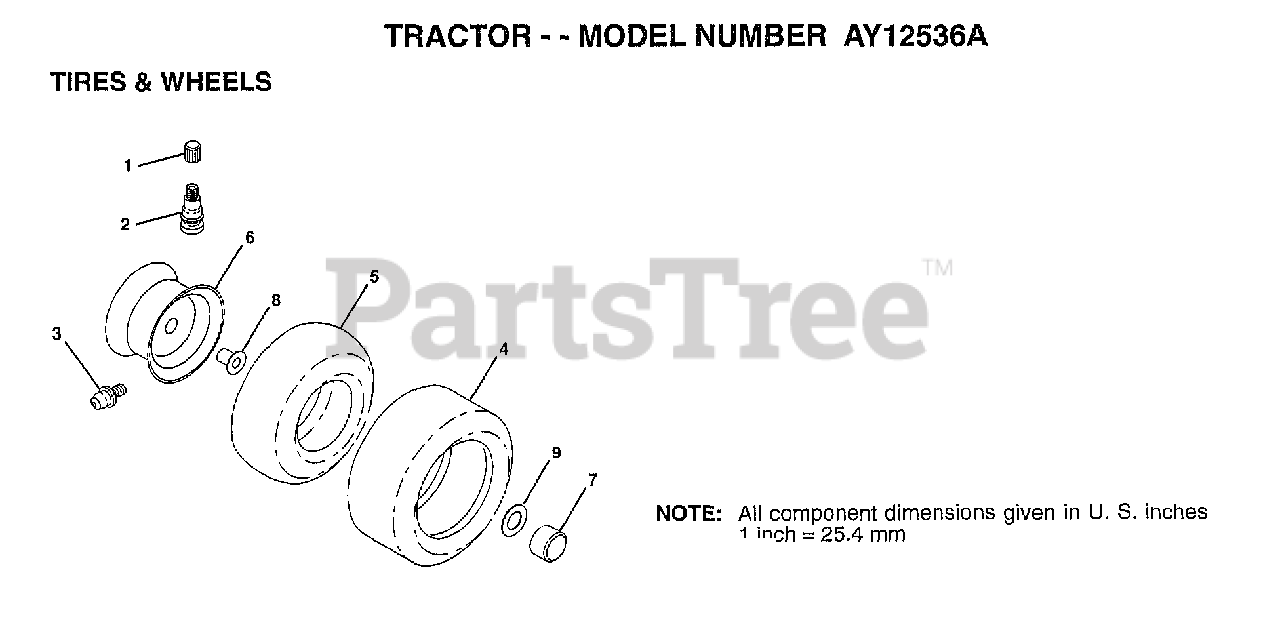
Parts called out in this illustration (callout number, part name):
1	VALVE CAP
2	VALVE STEM LT
3	FITTING LT
5	TUBE.5.3/4.5/6
5	TUBE.16X6.5/7.5-8
6	"RIM FRONT 6"""
6	"RIM ASM REAR 8"""
7	HUB CAP
8	"FLANGE, BEARING"
9	WASHER
